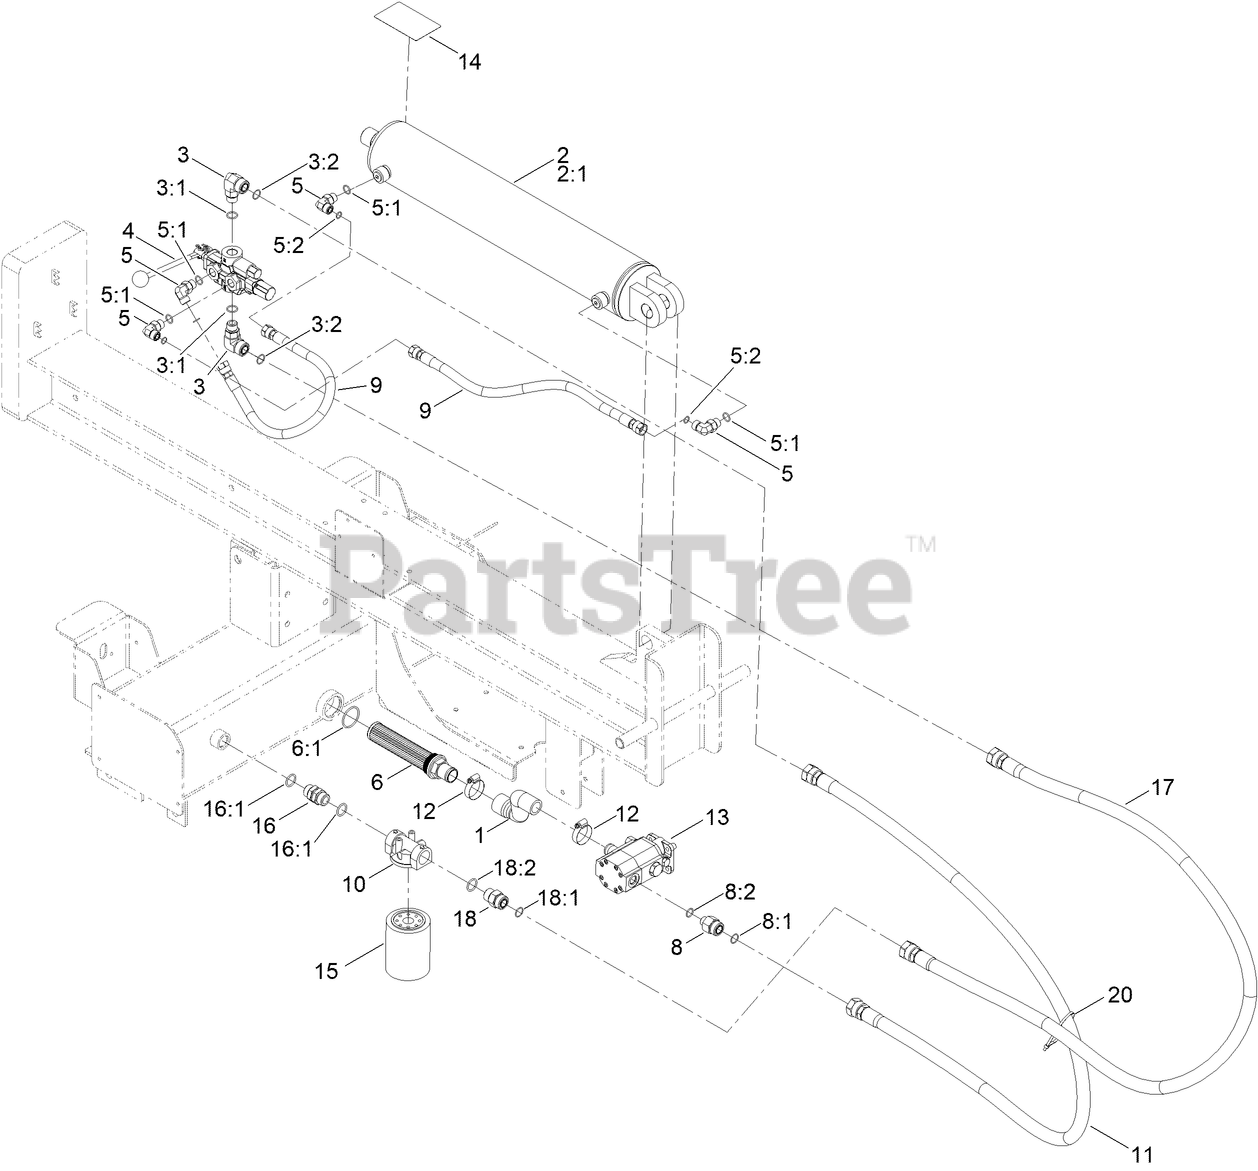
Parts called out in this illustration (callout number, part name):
1	HOSE-MOLDED
2	CYLINDER-HYDRAULIC
3	FITTING-HYD, 90 DEG
3:1	O-RING
3:2	O-RING
4	VALVE-CONTROL
5	FITTING-ELBOW, 90 DEG
5:1	O-RING
5:2	O-RING
6	STRAINER-TANK, HYDRAULIC
6:1	O-RING
8	FITTING-STRAIGHT
8:2	O-RING
9	HOSE ASM-HYD
10	HEAD-FILTER
11	HOSE ASM-HYD
13	PUMP-HYD
14	DECAL- CAUTION, CONTROL
15	FILTER-OIL, TRANSMISSION
16	FITTING-THREAD, STRAIGHT
16:1	O-RING
17	HOSE ASM-HYD
18	FITTING-HYD, STRAIGHT
18:1	O-RING
18:2	O-RING
20	TIE-CABLE
